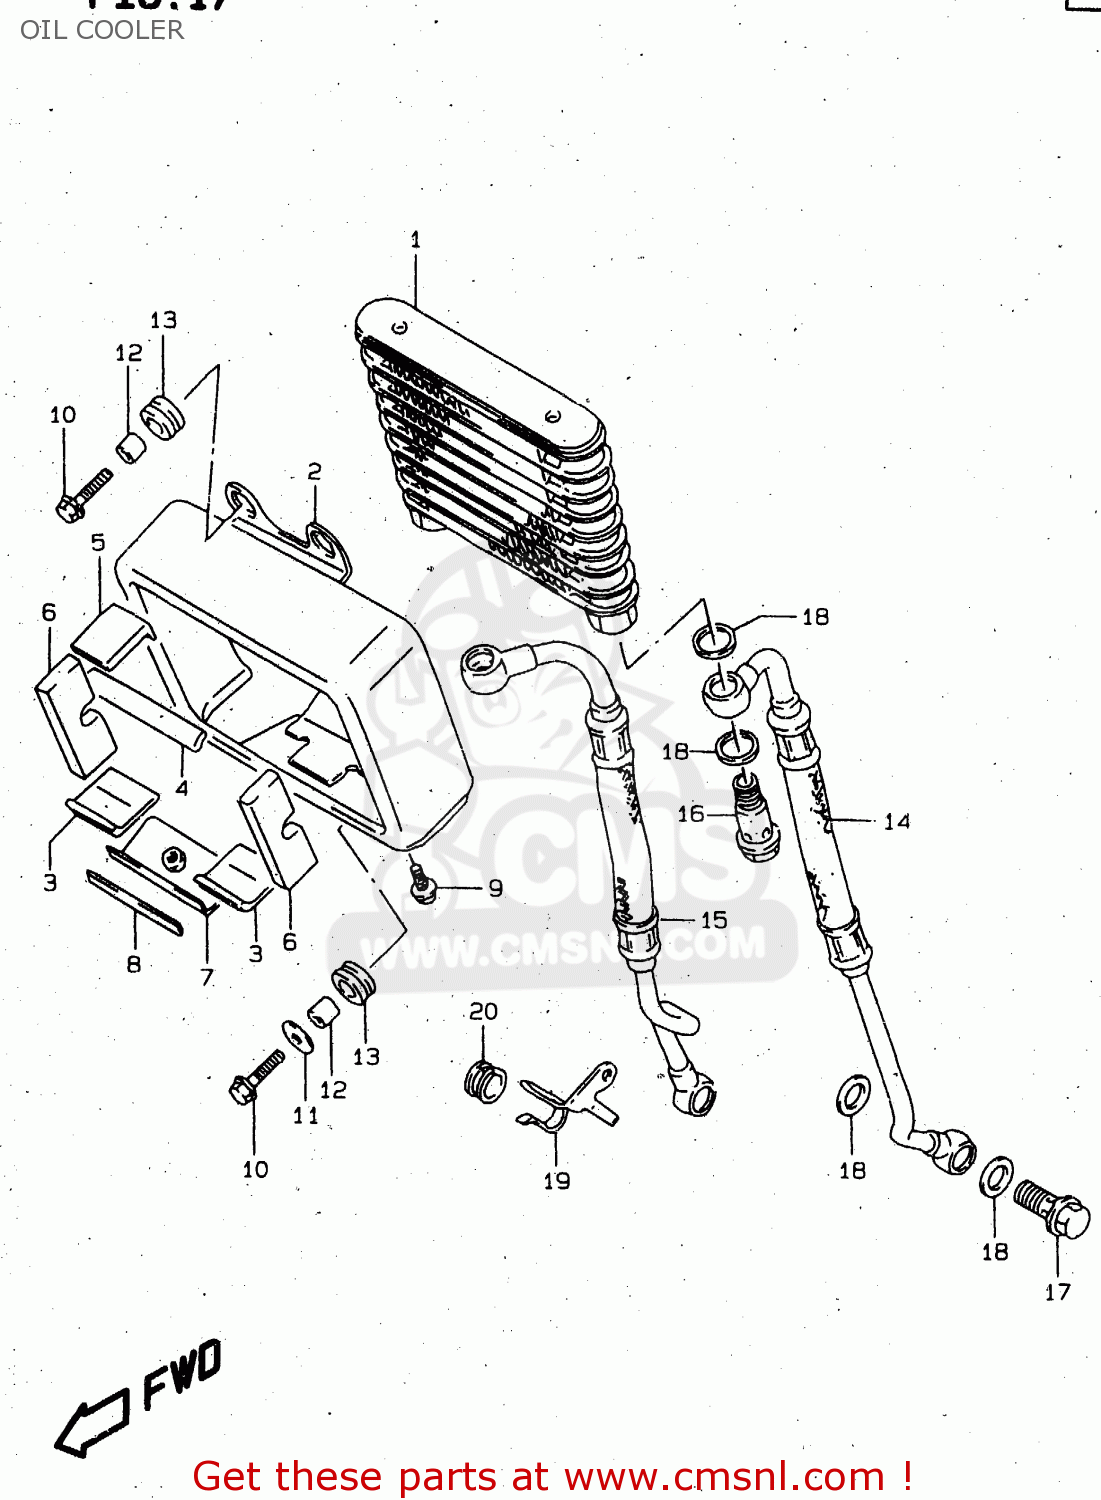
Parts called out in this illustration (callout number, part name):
1	COOLER ASSY,OIL
2	COVER,OIL COOLER
3	CUSHION,COOLER COVER LWR
4	CUSHION,CLLOER COVER UPR NO2
5	CUSHION,COOLER COVER UPR NO1
6	CUSHION,COOLER COVER SIDE
7	BRACKET,OIL COOLER
8	CUSHION,OIL COOLER BRACKET
9	BOLT
10	BOLT
11	WASHER(6.5X20X1.6)
12	SPACER(6.5X10X10)
13	CUSHION
14	HOSE,OIL COOLER,L
15	HOSE,OIL COOLER,R
16	BOLT UNION
17	BOLT UNION
18	GASKET(14X20X1.5) (NAS)
19	CLAMP,OIL COOLER HOSE,R
20	CUSHION
